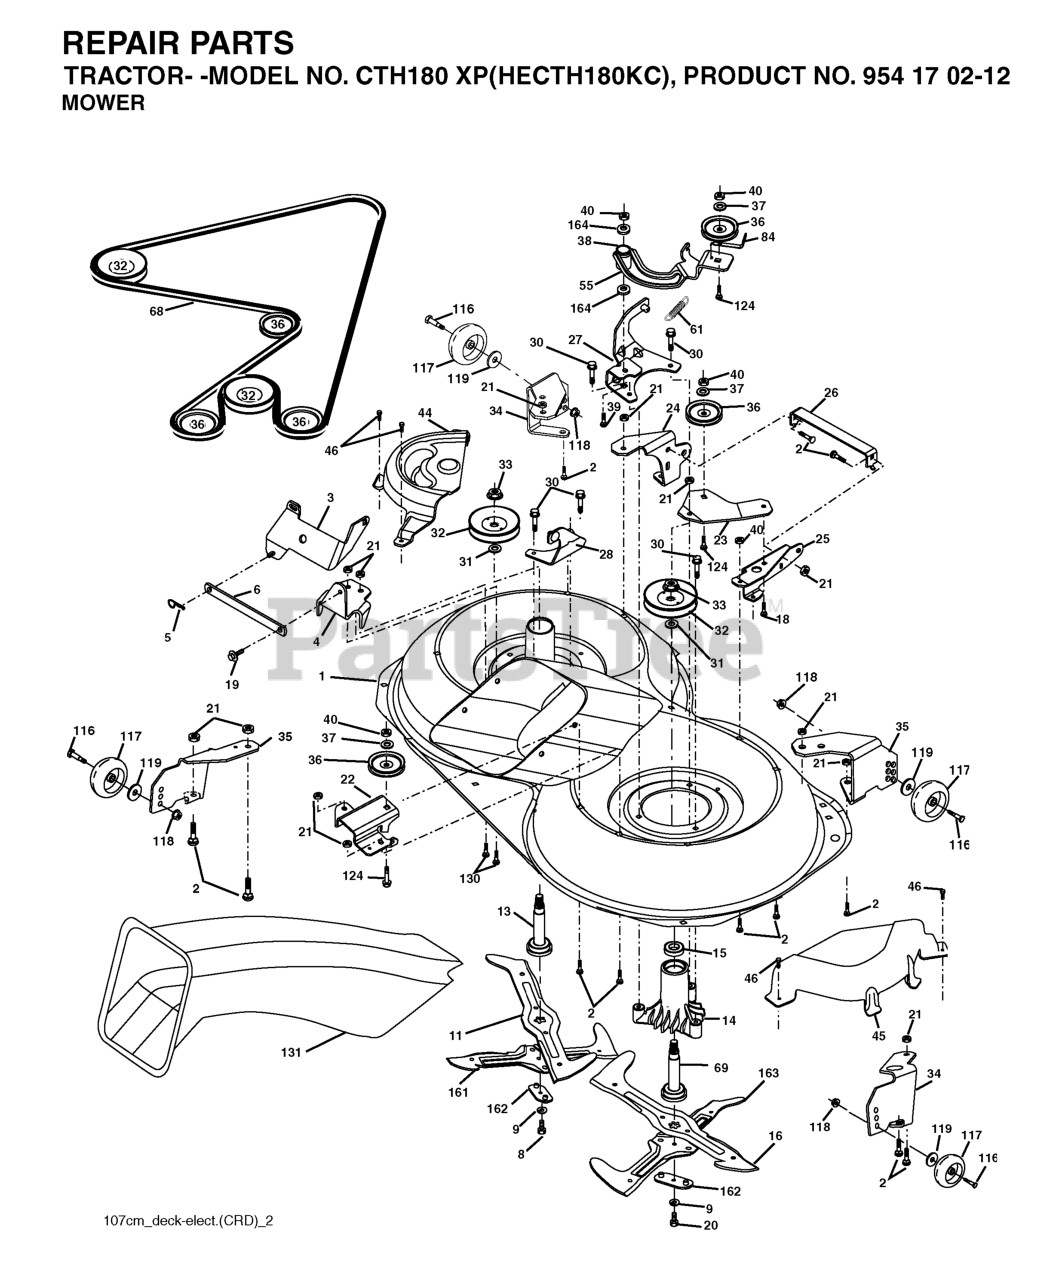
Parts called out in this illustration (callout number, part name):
1	Housing Asm. Mower 107 CRD
2	RP BOLT 5/16-18 X3/4 ZN/YEL GR
5	RETAINER-SPRNG RB
6	BAR.SWAY.92.CRD
8	BOLT.3/8-24X1.25 GR8
9	LOCKWASHER
11	BLADE.3N1.LH.CRD
13	SHAFT ASM VENT
14	HOUSING.MANDREL.VENTED (MACHD)
16	BLADE.3N1.RH.CRD
19	BOLT SHD 5/16-18
20	BOLT.3/8-24X1.25GR8. LHTHRD
21	LOCKNUT
22	BRACKET.IDLER.RR.107.CRD
25	BRACKET.SUSPENSION.RF.107.CRD
26	BRACE.SUPT.SUSP.FRT.CRD
28	BRACKET
30	SCREW, WASHER HEAD
31	WASHER.SPACER.MANDREL
33	NUT, FLG TOPLOCK 9/16"
36	PULLEY.IDLER.4.25
37	WASHER
45	COVER.MANDREL.RH.CRD
46	SCREW.1/4-20X5/8
55	ARM.IDLER.107.CRD
68	HEX-BELT 107 MOWER
69	SHAFT.ASM.W/LWR.BRG.RH.THREAD
84	KEEPER, BELT IDLER
116	SHOULDER BOLT
117	WHEEL GAGE DONUT
118	LOCKNUT
119	WASHER.5/16.FLAT.STE.STD.
124	BOLT.3/8-16X1.50
130	BOLT.CARR.SQNK.5/16-18UNC.X3/4
131	CHUTE BAGGER
163	BLADE.CROSS.RH.CRD.107
164	BRNG T
